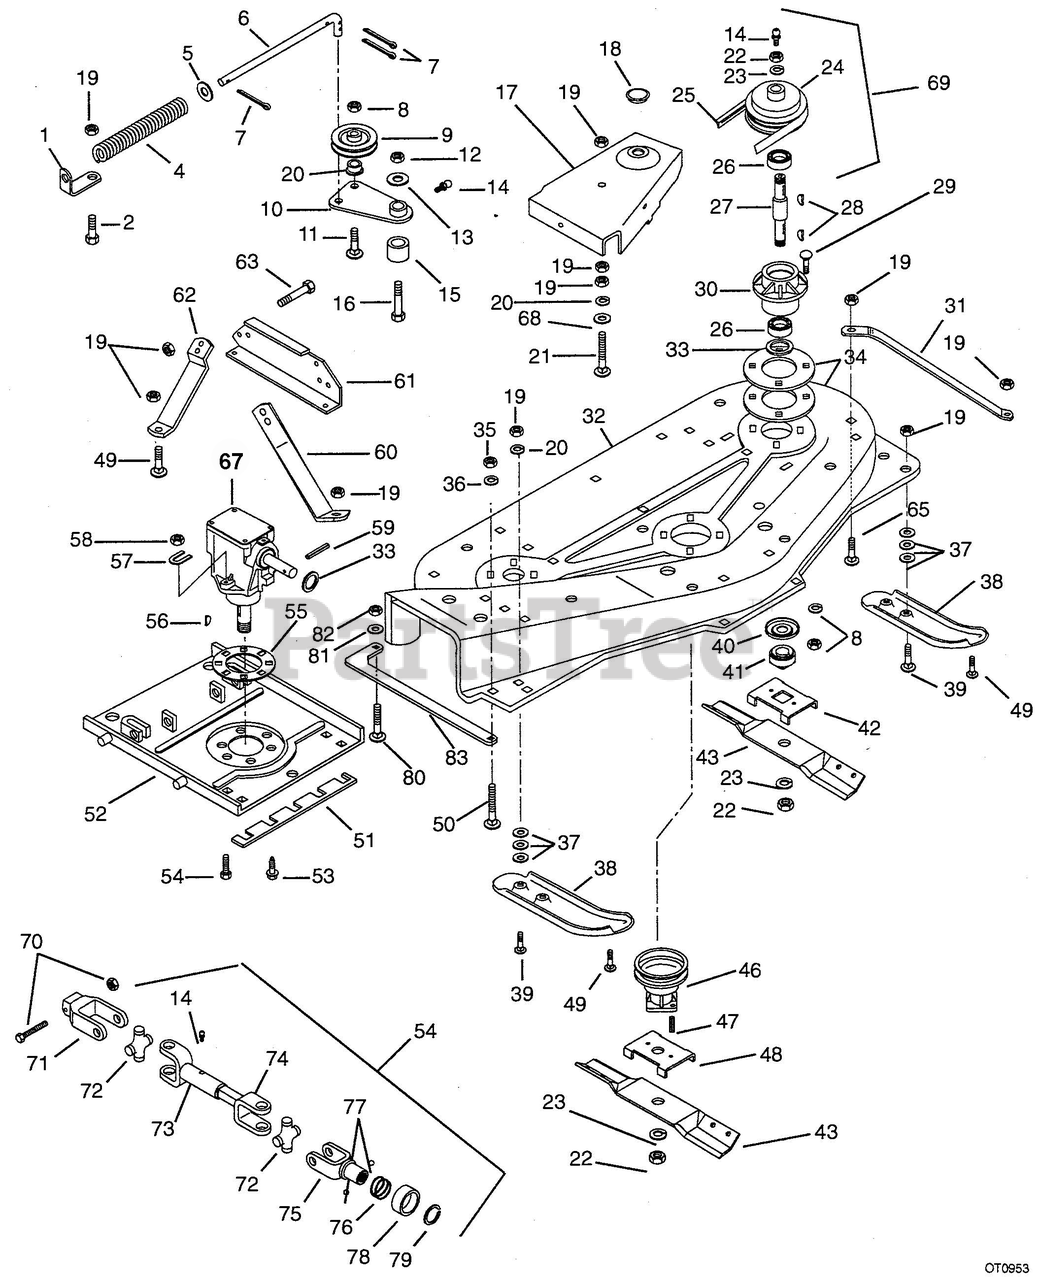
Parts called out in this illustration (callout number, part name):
1	BRACKET
2	@BLT-HEX .31-18X.75 GR5 YWZC
3	@NUT-LK-CTR .31-18 YWZC
4	SG-COMP .106X.63X 12.0 WLD 62
5	@WSHR-FL-STL.406X.812X.065 YWZ
6	ROD-IDLER SPRING
7	@PIN-CTR .09X.75 EXTPRSQCT YWZ
8	@NUT-LK-CTR-JAM .375-16 YWZC
9	IDLER-FLAT 4.00 X .38 NWHAMSHR
10	IDLER ARM W/ZERK
11	BLT-BTHD .38-16X1.25 GR5
12	NUT-LK-CTR-JAM .50-13 YWZC(ND)
13	@WSHR-FL-STL.531X1.06X.095YWZC
14	FTG-LUBE .25-28X.256 YWZC
15	SPACER .512X.747X.968
16	@BLT-HEX .50-13X1.50 GR5 YWZC
17	BELT COVER R H 42"
17	BELT COVER L H 42"
18	PLUG BUTTON 1.50
19	@NUT-LK-TOP-FLG .31-18 YWZC
20	SPACER -FLANGED .390X.500X.781
21	BLT-RDHDSQNK .312-18X3.25 YWZC
22	NUT-JAM .75-10 YWZC
23	@WSHR-LK .75X.188 REG YWZC
25	V-BELT, HA-WRAPPED
26	BRG-BALL .750X1.781X.61
27	SPINDLE SHAFT W/ZERK
28	KEY-WDRF .188X.625X.25 SAE 61
29	@BLT-RDHDSQNK .38-16X.75 G2YWZ
30	SPINDLE HOUSING
31	BRACE, SKID - L.H.
32	MOWER PAN W/DECALS 42"
33	WSHR-FL-STL .754X1.000X.032 YZ
34	SPACER, SPINDLE
35	@NUT-HEX .38-16 YWZC
36	WSHR-LK .375X.115 HVY YWZC
37	@WSHR-FL-STL.38X.875X.083 YWZC
39	@BLT-RDHDSQNK .31-18X1.00 G5YZ
40	BEARING SLINGER
41	RETAINER HUB
42	BLADE TRAY 42
43	BLADE 42 IN
47	PIN-GRV .188X.75 TP A
48	BLADE TRAY - GT 42
49	@BLT-RHDSSQNK .31-18X.75 G5YZ
50	BLT-HEX.38-16X2.5FTHD GR2 YWZC
52	MOUNTING PLATE
53	@SCR-TAP .31-18X1.00 HWH TR YZ
54	@BLT-HEX .31-18X1.25 GR5 YWZC
56	KEY-WDRF .25X.750X.313 SAE91
57	YOKE
58	@NUT-LK-CTR .31-18 YWZC
59	PIN-ROLL .125X1.00
60	BRACE-RIGHT FRONT
61	BRACKET-BRACE
62	BRACE-RIGHT REAR
63	@BLT-HEX .31-18X.75 GR5 YWZC
64	PTO ASSEMBLY SEE L-355
65	@BLT-RHDSSQNK .31-18X.75 G5YZ
67	MOWER GEAR CASE 42 IN KIT
68	@WSHR-FL-STL.344X.688X.065YWZC
69	SPINDLE ASSEMBLY
70	SHEARBOLT & NUT ASSEMBLY
72	JOURNAL CROSS & BEARING ASSEMB
73	SLIP YOKE
74	YOKE AND SHAFT
75	Q.D. YOKE
75	YOKE
76	SPRING
77	BALL,.312 GRD 2000,CBN STL,GM#
78	COLLAR
79	RG,SNAP
79	PIN-HAIR INT .18X1.18X3.25 PL
80	@BLT-RDHDSQNK .31-18X.75 G5YZ
81	@WSHR-LK .31X.078 REG YWZC
82	@NUT-LK-CTR .31-18 YWZC
83	GUARD, TOE-42"-ORANGE
